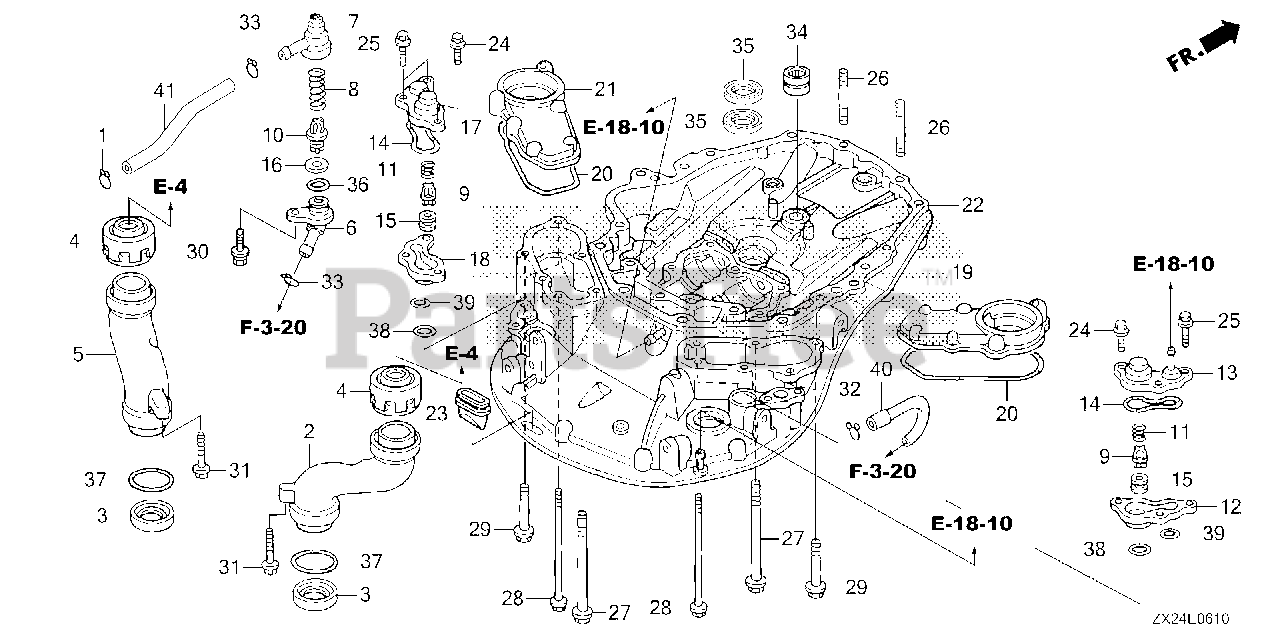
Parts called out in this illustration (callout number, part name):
1	CLIP, TUBE
2	GUIDE, R. EX. *TGRAY* (GRAY)
3	SEAL, EX. GUIDE
4	SEAL B, EX. GUIDE
5	GUIDE, L. EX. *TGRAY* (GRAY)
6	COVER, FLUSH VALVE *NH8* (DARK GRAY)
7	CASE, FLUSH VALVE
8	SPRING, FLUSH VALVE
9	VALVE, RELIEF
10	VALVE, FLASH
11	SPRING, RELIEF VALVE
12	SPACER, R. RELIEF VALVE *TGRAY* (GRAY)
13	COVER, R. RELIEF VALVE
14	GASKET, RELIEF VALVE COVER
15	GASKET, RELIEF VALVE
16	GASKET, FLASH VALVE
17	COVER, L. RELIEF VALVE
18	SPACER, L. RELIEF VALVE *TGRAY* (GRAY)
19	COVER, R. WATER JACKET
20	GASKET, WATER JACKET COVER
21	COVER, L. WATER JACKET
22	CASE, MOUNT *NH8* (DARK GRAY)
23	RUBBER, MOUNT CASE SEAL
24	BOLT, FLANGE (6X22)
25	BOLT, FLANGE (6X32)
26	BOLT, STUD (10X45)
27	BOLT, FLANGE (8X100)
28	BOLT-WASHER (6X121)
29	BOLT, FLANGE (8X30)
30	BOLT-WASHER (6X29)
31	BOLT, FLANGE (6X40)
32	CLIP, TUBE (B10)
33	CLIP, TUBE (B12.5)
34	BEARING, NEEDLE (20X28X13) (SOLID)
35	SEAL, WATER (22X35X7)
36	O-RING (16MM)
37	O-RING (49.4X3.1)
38	O-RING (33.5X2)
39	O-RING (23.5X2)
40	TUBE, WATER CHECK
41	TUBE, FLUSH VALVE
